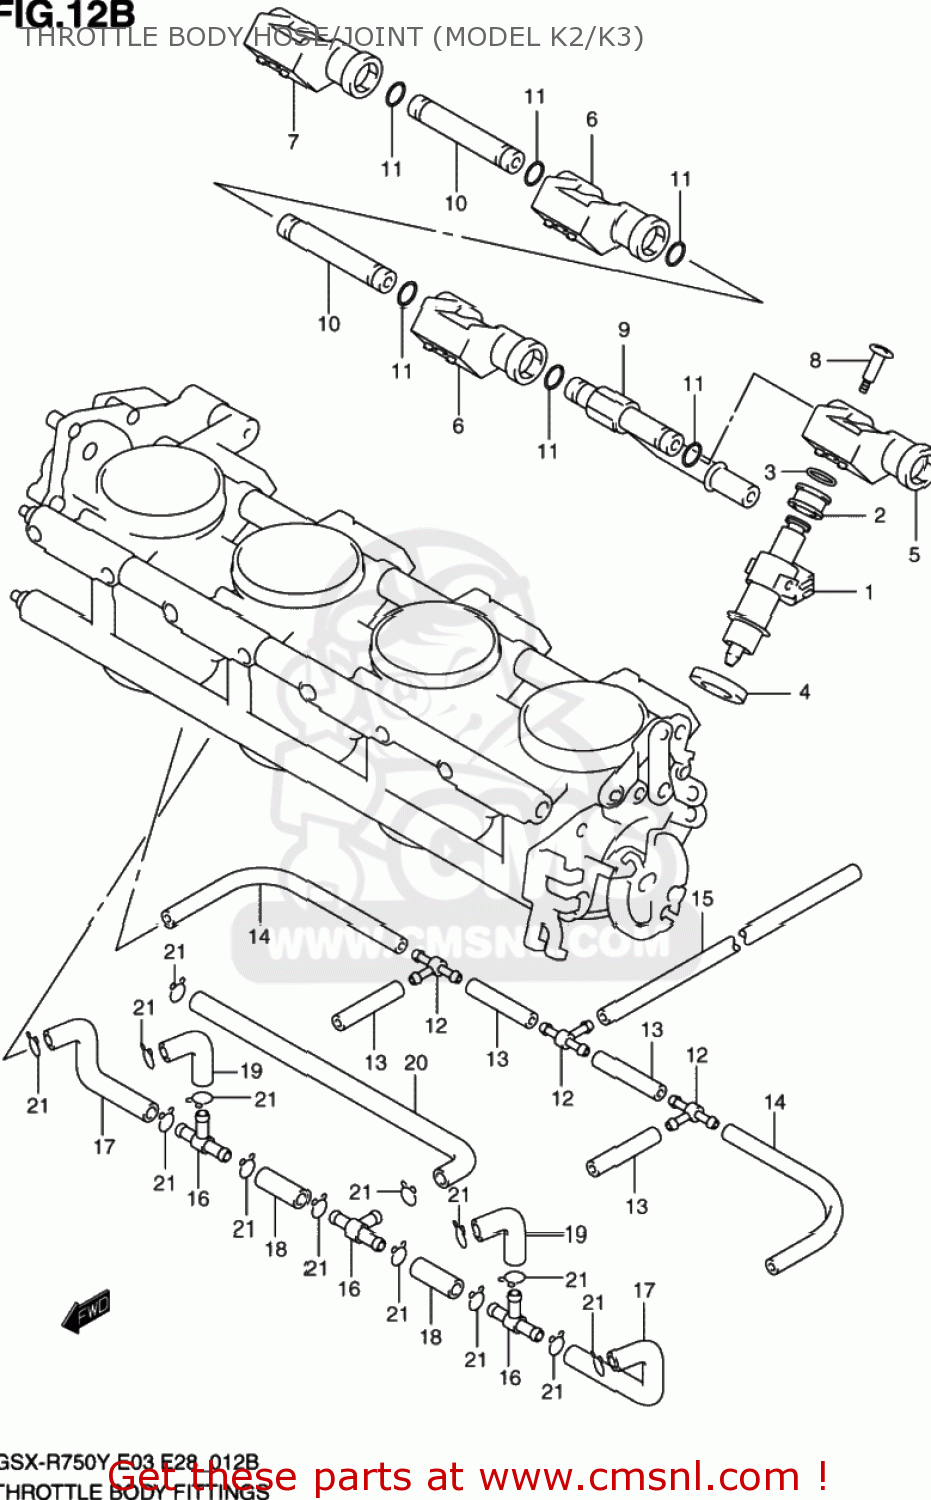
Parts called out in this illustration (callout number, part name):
1	INJECTOR ASSY
2	RING,CUSHION
3	O RING
4	RING,SEAL
5	JOINT,NO.1
6	JOINT,NO.2,3
7	JOINT,NO.4
8	SCREW
9	JOINT
10	JOINT
11	O RING
12	JOINT
13	HOSE,RUBBER(L:35)
14	HOSE,RUBBER(L:100)
15	HOSE,RUBBER(3X7X170)
16	JOINT
17	HOSE,RUBBER(L:80+25)
18	HOSE,RUBBER(L:35)
19	HOSE,RUBBER(L:30+30)
20	HOSE,RUBBER(L:200+30)
21	CLIP
